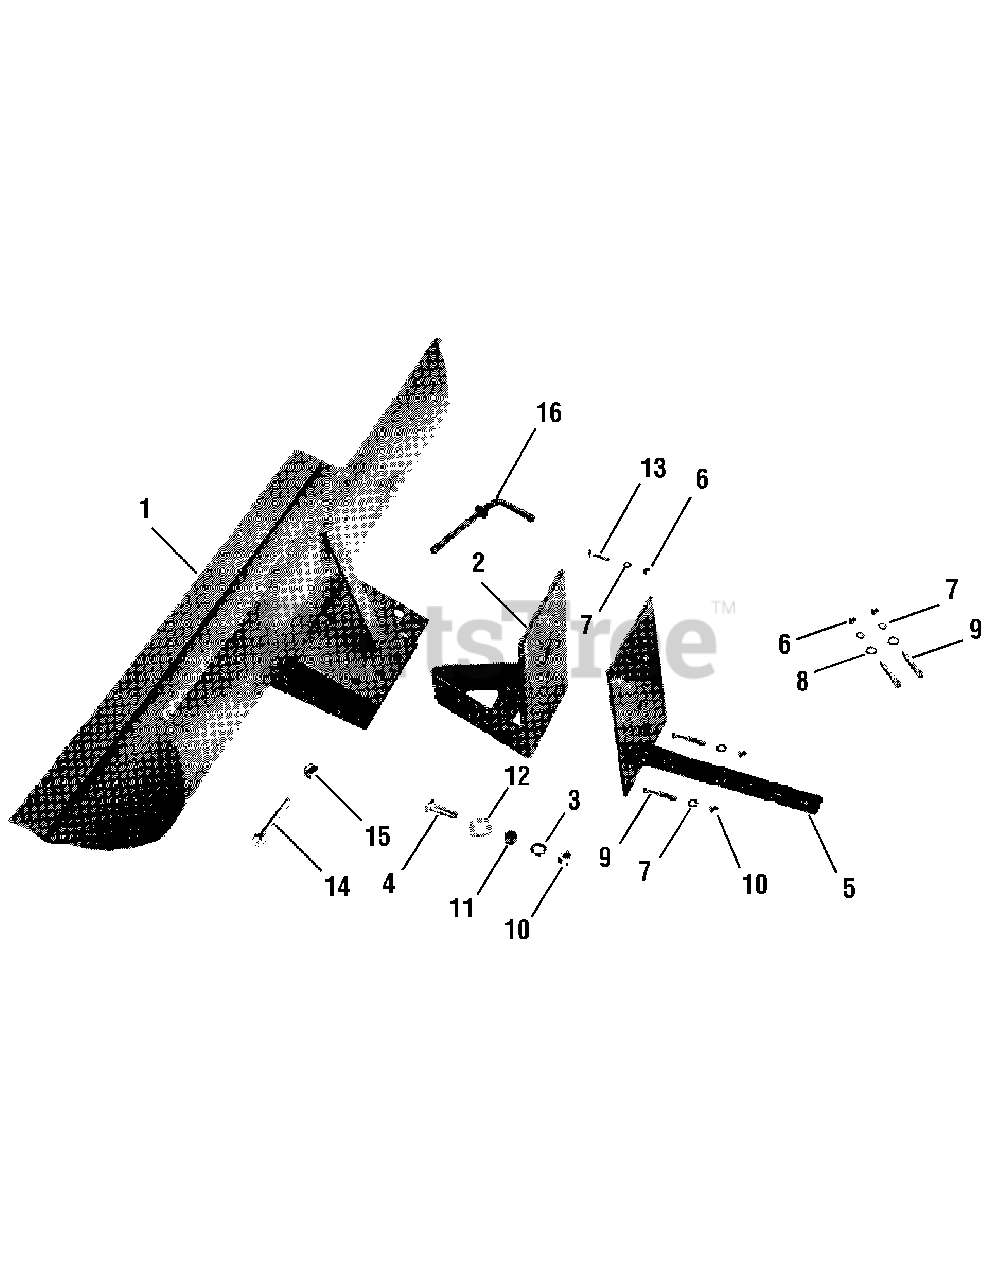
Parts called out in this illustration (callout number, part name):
1	Dozer/Snow Blade
2	Swivel Bracket, (A-Frame)
3	Lockwasher, 1/2"
4	Hex Head Bolt, 1/2--13 x 1-1/2,
5	Blade Mounting Brack
6	Hex Head Nut, 5/16-18
7	Lockwasher, 5/16
8	Washer, Plain, 5/16
9	Hex Head Screw, 5/16-18 x 1-3/4
10	Hex Nut, 1/2"
11	Bushing
12	Flat Washer, 1/2"
13	Hex Head Screw, 5/16-18 x 1-1/4
14	Hex Head Screw, 1/2-13 x 3
15	Hex Locknut, 1/2 x 13
16	Index Pin
